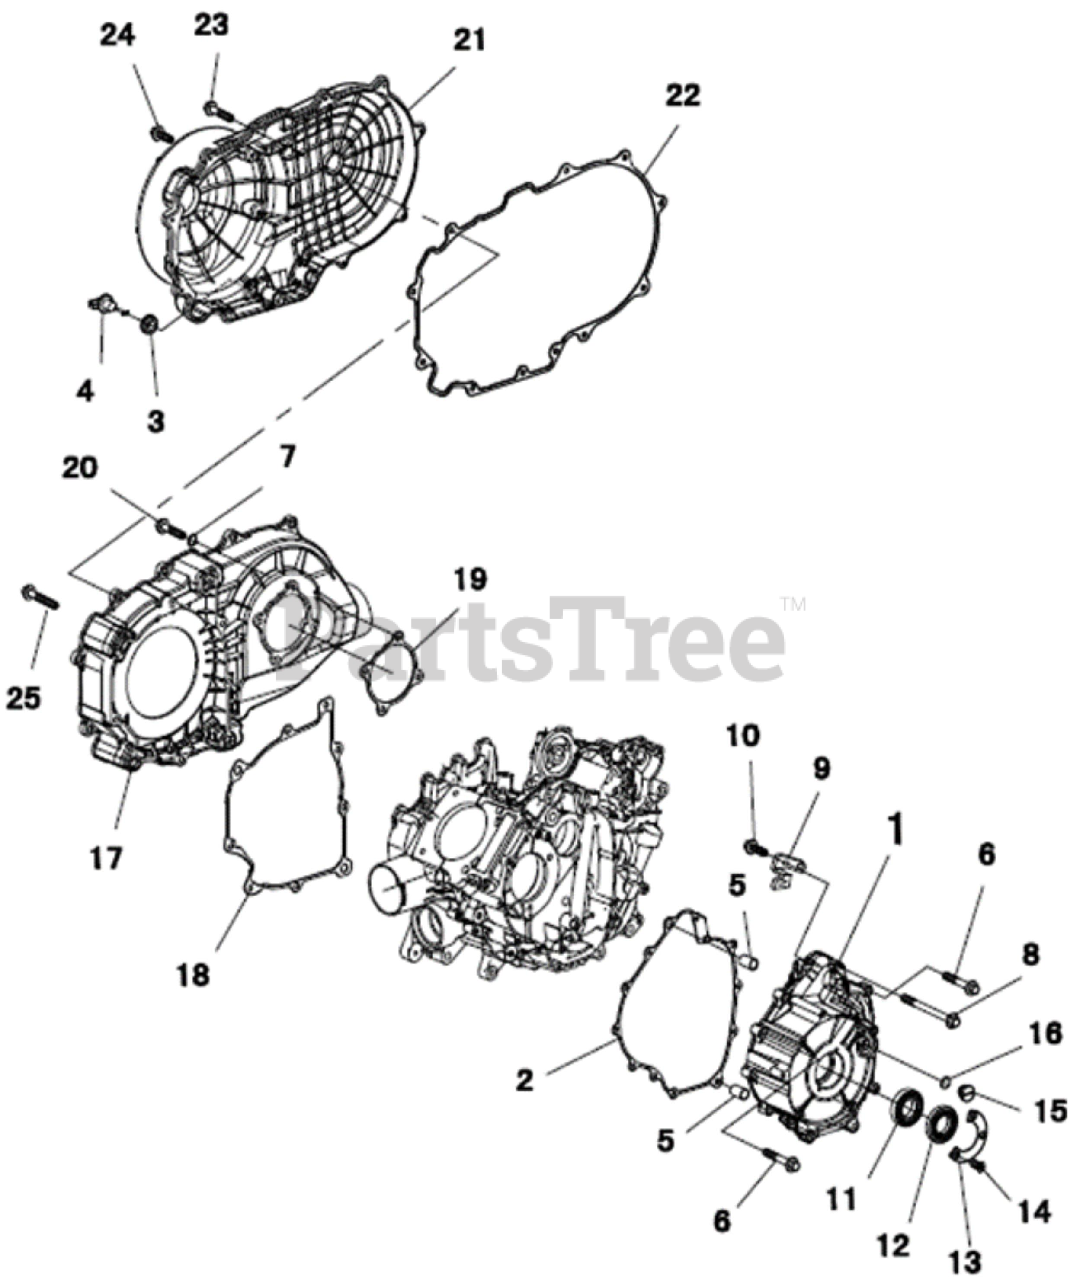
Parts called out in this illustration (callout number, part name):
1	Left Crankcase Cover
2	Gasket,Left Crankcase Cover
3	RubberSheath
4	Plug,Clutch Cover
5	Pin,Dowel 10X16
6	Hexagon flange bolts M6X30
7	Spring Washer 6
8	Hexagon flange bolts M6X40
9	Stator wire guard plate
10	Hexagon flange bolts M6X12
11	Bearing 60/28
12	Oil Seal 28X52X8.5
13	Press Plate,Oil Seal, LeftfFront
14	Cross recessed countersunk head screw M5X12
15	Peep Hole Cover
16	O-Ring 13.4X2.35
17	Cover,Clutch,Inner
18	Seal,Clutch Inner Cover
19	Seal,Clutch Inner Cover
20	Hexagon flange bolts M6X32
21	Cover,Clutch,Outer
22	Seal,Clutch Cover
23	Hexagon flange bolts M6X25
24	Hexagon flange bolts M6X16
25	Hexagon flange bolts M6X50
